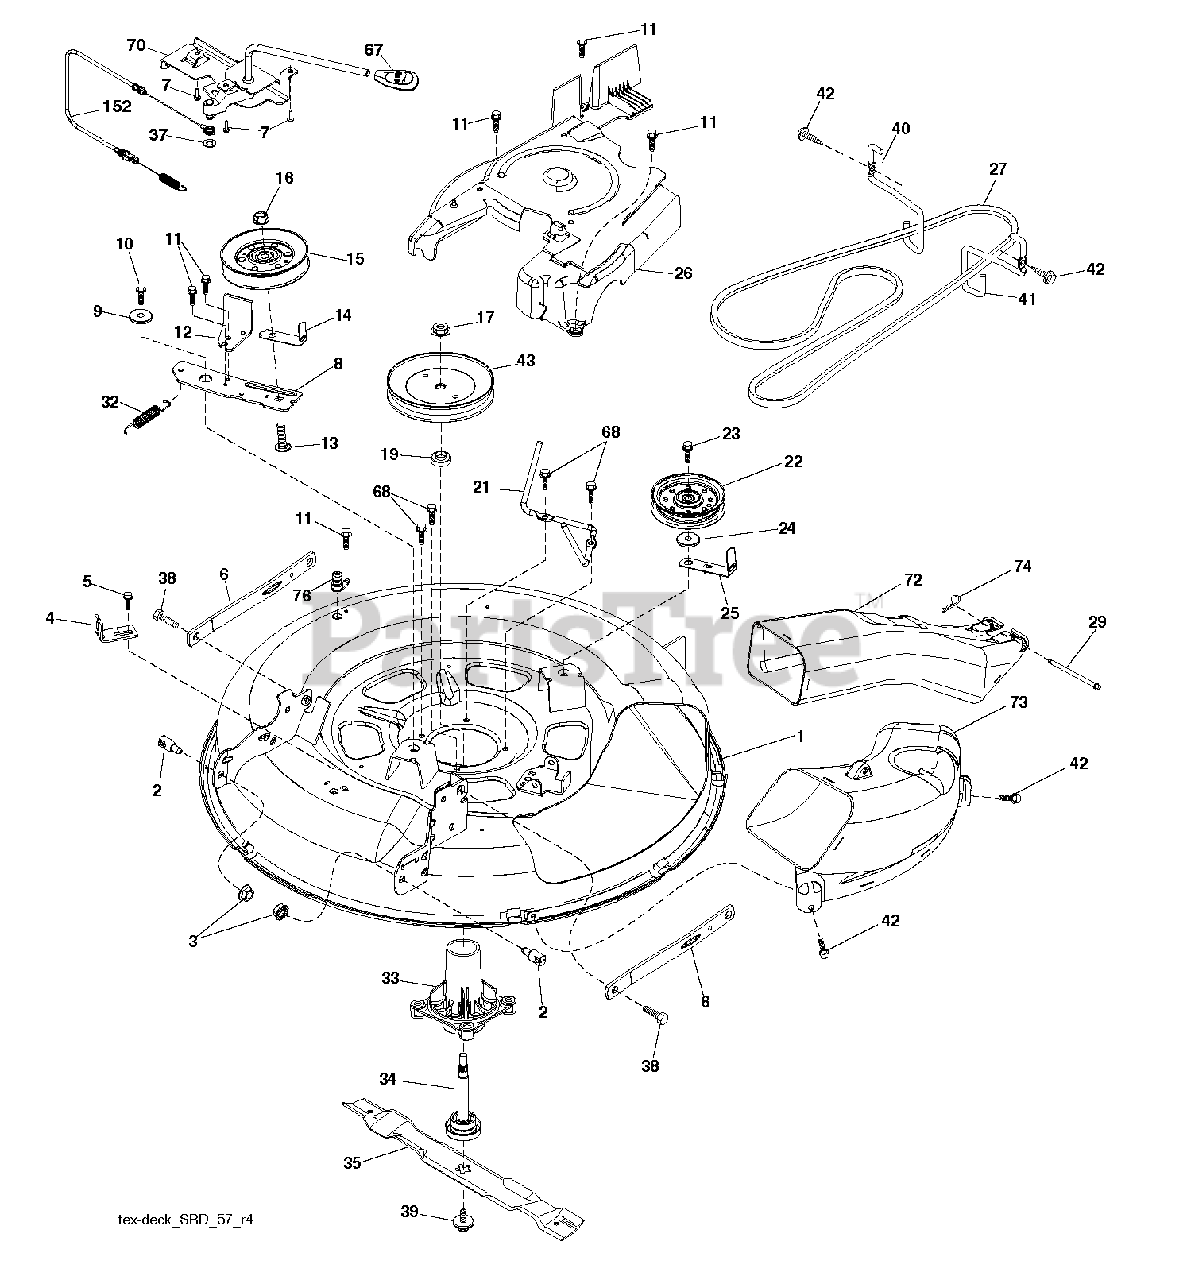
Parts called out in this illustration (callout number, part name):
1	DECK.WELDMENT.PNT.30"SRD
2	STUD.FASTNER.W/ANTI-ROTATE
3	NUT LOCK HEX FLANGE 5/16-18
4	BRACKET.CLUTCH.CABLE
5	BOLT.5/16HEX.WHS.HD
6	ARMS.SUSP.MOWER.REAR.SRD
7	SCREW.#10 X 0.750.BOS
8	ARM.IDLER.30"SRD
9	SPACER.RETAINER
10	SCREW 3/8-16X1
11	SCREW.1/4-20X5/8
12	RP ARM.BRAKE.MOWER.38"LH.TEX
13	BOLT.3/8-16X1.50
14	KEEPER, BELT IDLER
15	PULLEY.IDLER.4.25
16	NUT LOCK FLG 3/8-16 UNC
17	NUT.FLANGE.LOCK.TOP
19	BEARING.MANDREL.TOP.EXTENDED
21	KEEPER.BELT.MANDREL.30"
22	PULLEY.IDLER.FLAT.46.PR.DR.
23	SCREW LT
24	WASHER
25	KEEPER.BELT.30"SRD
26	COVER.ASM.MANDREL.30"
27	V-BELT.DRIVE.MOWER.30"
29	PIN.HINGE.30".SRD
32	SPRING RETURN
33	HOUSING.MANDREL.4PT.
34	SHAFT ASM.MNDRL.N/GREASEABLE
35	BLADE.MOWER.BAGGING.30"
37	WASHER
38	BOLT.SHOULDER
39	SCREW.SEMS.7/16-20X1.HEX.HEAD
40	KEEPER.BELT.ENGINE.LH.LT.SRD
41	KEEPER.BELT.ENGINE.RH.LT.SRD
42	SCREW, 3/8-16X3/4
43	PULLEY, MANDREL 6.5 PD
67	HANDLE.CLUTCH.CABLE.LT
68	BOLT.HEX.WASHR.HED.313-18X1.19
70	CLUTCH.ASM.MANUAL.LT.PRED
72	CHUTE.UPPER.SRD.30R"
73	CHUTE.LOWER.SRD.30R"
74	Retainer Spring
76	PORT.WASHOUT
152	CABLE.CLUTCH.MANUAL.
